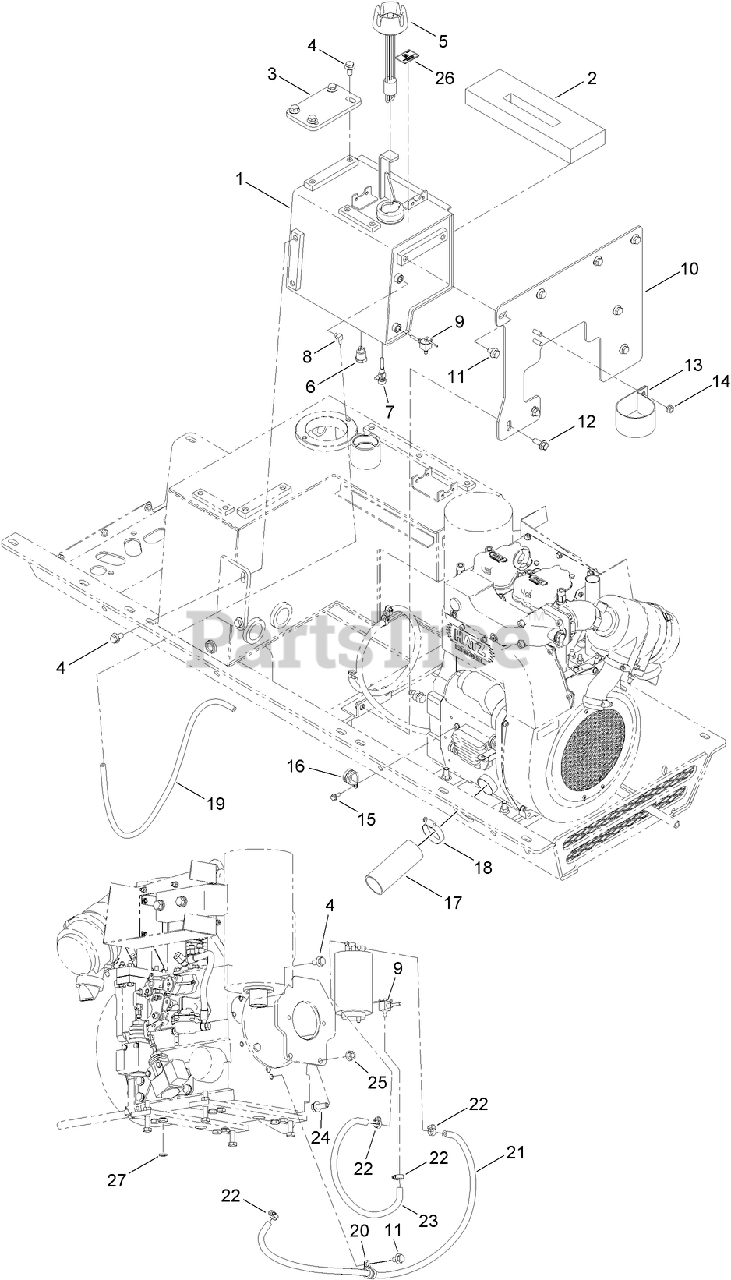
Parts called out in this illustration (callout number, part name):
1	CELL-FUEL TANK
2	ISOLATOR-LIFTEYE
3	PLATE-MOUNTING, HYD FUEL
4	SCREW-HHF
5	GAUGE-FUEL
6	PLUG-HH, MAGNETIC
7	VALVE AND STRAINER ASM
8	FITTING-HYD, ELBOW
9	VALVE-STRAINER
10	SHIELD-HEAT
11	SCREW-HHF
12	SCREW-HHF
13	STRAP-SEPARATOR, WATER
14	NUT-HF
15	SCREW-HHF
16	CLAMP
17	HOSE-BREATHER
18	CLAMP-HOSE
19	HOSE-FUEL, RETURN
20	CLAMP
21	HOSE-FUEL
22	CLAMP-WORM
23	HOSE-FUEL
24	SCREW-HHF
25	NUT-HF
26	DECAL-ULTRA LOW SULFUR DIESEL
27	WASHER-FLAT
